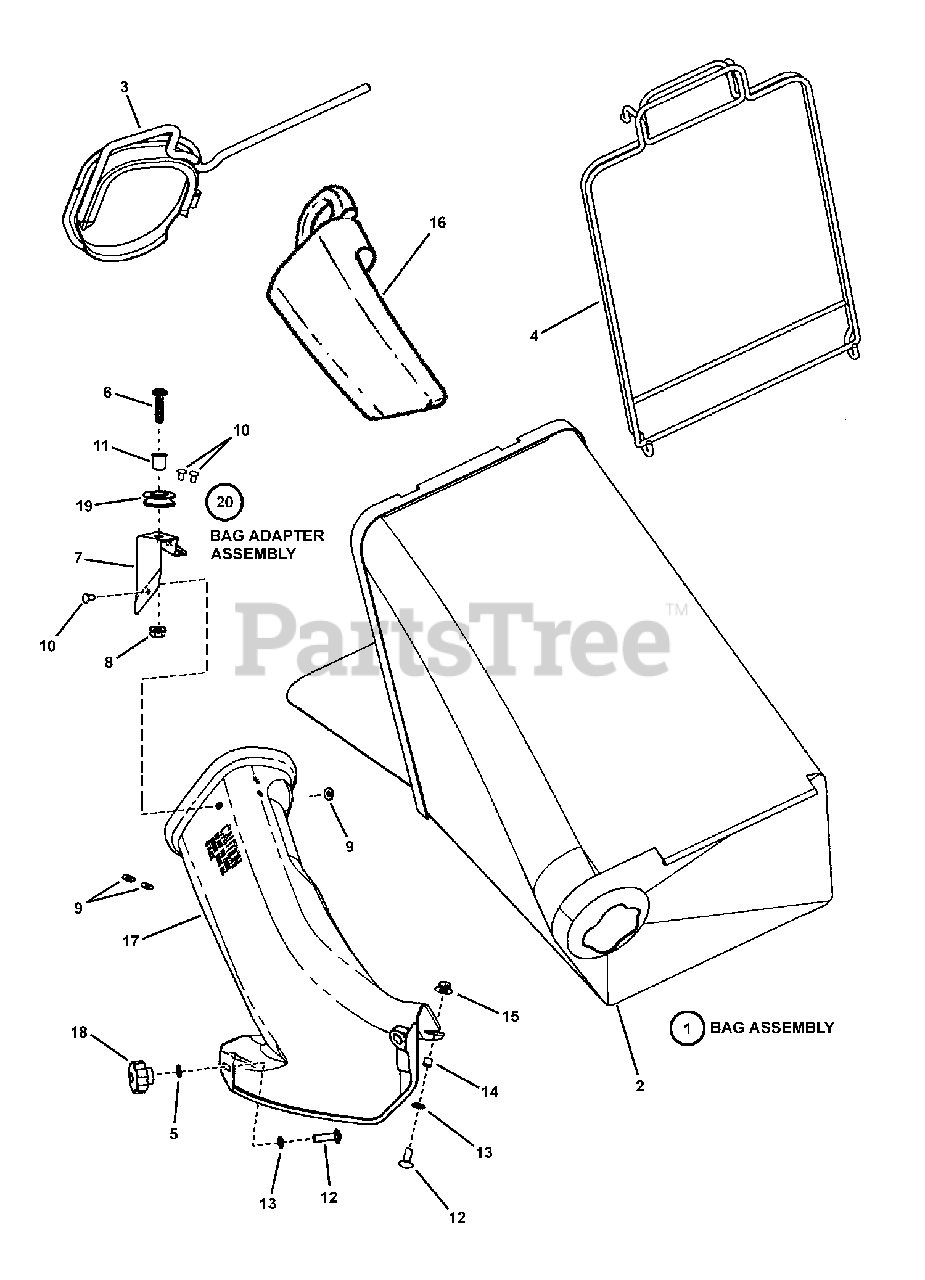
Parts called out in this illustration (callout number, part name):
1	BAG ASSEMBLY (Door)
2	GRASS BAG, (Door w/Gray Letters)
3	CONNECTOR, Grass Bag (weldment)
4	ASSEMBLY, Bag Wire (12" Wide)
5	WASHER, 5/16" Internal/External Tooth Lock
6	SCREW, 5/16-18 x 1-1/4" Pan Head Machine
7	BRACKET, Rope Guide
8	NUT, 5/16-18 Hex Flange Lock, GR 5
9	WASHER, 15/32" Flat
10	RIVET, 3/16 x .344
11	BUSHING, Flange, .381 x .625 x .62
12	BOLT, 5/16-18 x 3/4" Short Neck Carriage GR 5
13	RETAINER, 5/16" Bolt
14	SPACER, .316 I.D. x .375 O.D. x .310 thick
15	NUT, 5/16-18 Hex Large Flange Center Lock
16	PLUG, Chute Adapter
17	ADAPTER, Grass Bag
18	KNOB, Fluted, 5/16-18 x .633
19	PULLEY, Nylon
20	ASSY, Grass Bag Adapter
